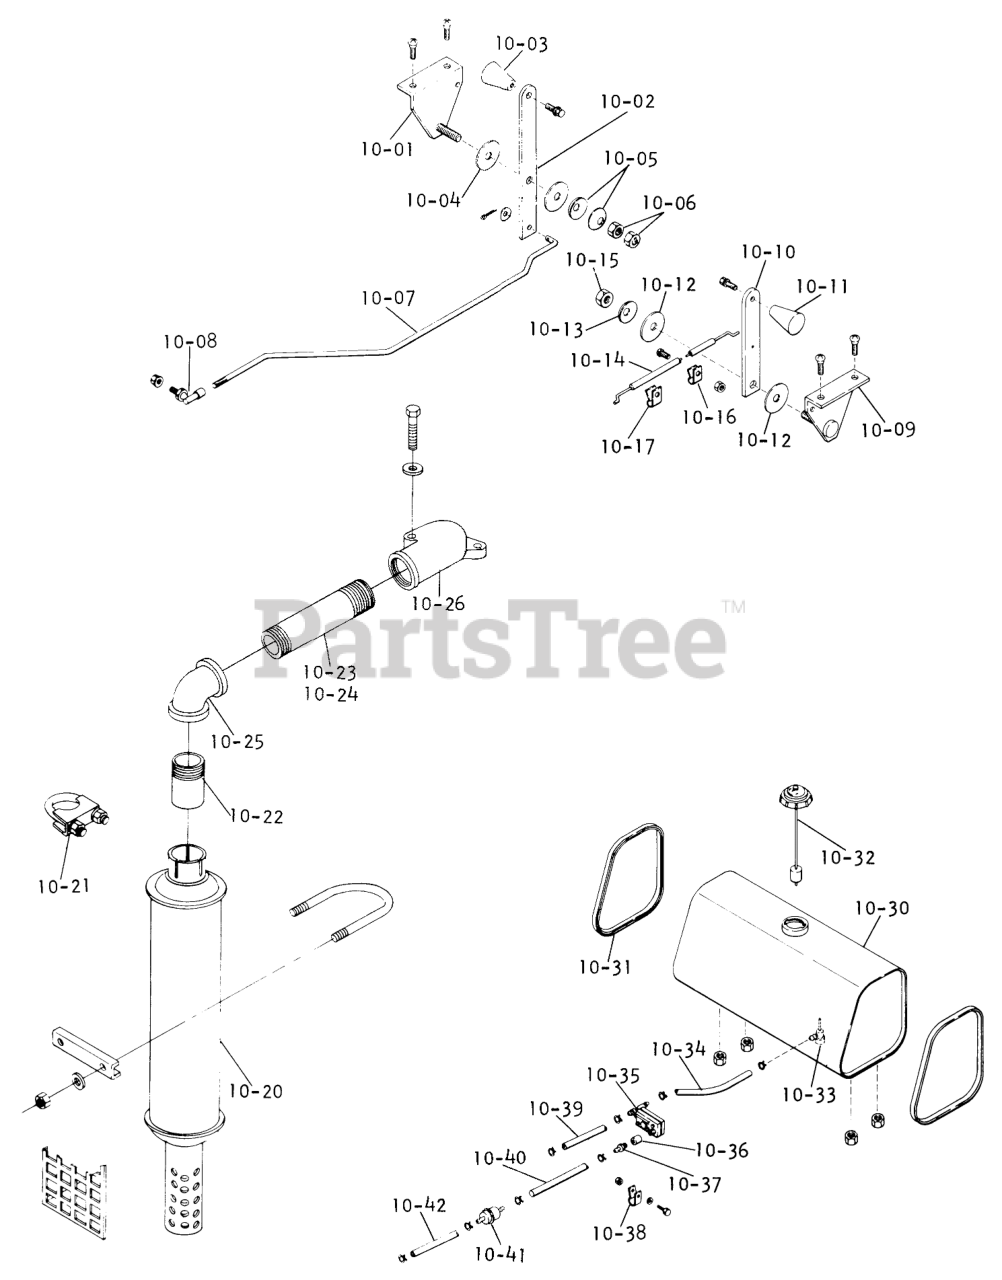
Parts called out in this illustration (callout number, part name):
10-01	Bracket-Choke
10-02	Handle-Throttle
10-04	FRICTION WASHER
10-05	WASHER-SPRING DISC
10-07	Rod-Throttle
10-08	BALL JOINT ASSY R
10-09	Bracket-Choke
10-10	HANDLE
10-12	FRICTION WASHER
10-13	WASHER-SPRING DISC
10-14	CABLE CHOKE CONTROL
10-15	3/8-16 E.S.
10-16	CLIP BOWDEN WIRE
10-17	THROTTLE CONTROL CLP
10-20	Muffler
10-21	ASSY-MUFFLER CLAMP
10-22	Nipple
10-23	Nipple 1" Pipe x 2"
10-24	Nipple-Exhaust 1 X 5
10-25	Elbow 90 X 1
10-26	Fitting Exhaust RH
10-26	Bolt 5/16-18 x 11/4
10-30	Fuel Tank
10-31	Edge Trim
10-32	GAUGE CAP
10-33	FILTER & VALVE ASSY
10-34	Fuel Hose
10-35	Pump Fuel
10-36	Coupling 1/8" Pipe
10-37	Straight Fitting
10-38	CLAMP-HOSE
10-39	Fuel Hose
10-40	Hose-Fuel
10-41	Filter
10-42	Fuel Hose
